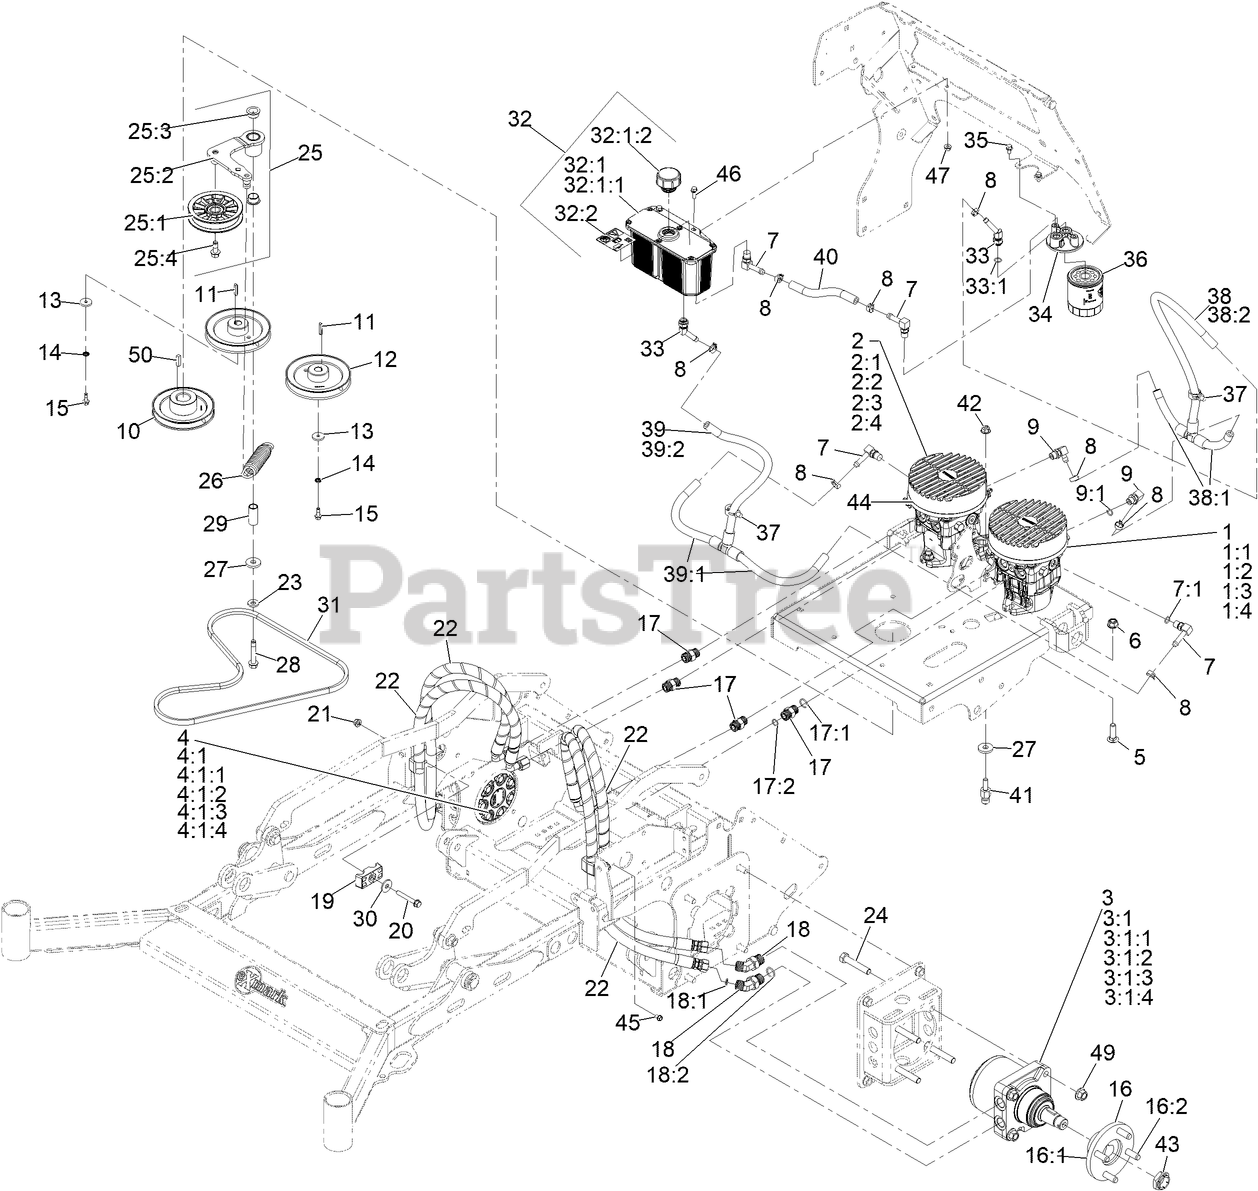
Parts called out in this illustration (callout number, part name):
1	PUMP-12CC LT W/SHOCK VALVE
1:1	KIT, 10CC/12CC PUMP KIT
1:2	SEAL OVERHAUL KIT
1:3	GUARD-PUMP
1:4	PUMP-COOLING
2	PUMP-12CC RT W/SHOCK VALVE
2:1	KIT, 10CC/12CC PUMP KIT
2:2	SEAL OVERHAUL KIT
2:3	GUARD-PUMP
2:4	PUMP-COOLING
3	MOTOR, TL240 LH
3:1	SEAL KIT
4	MOTOR, TL240 RH
4:1	SEAL KIT
5	BOLT-CARR
6	NUT-HF, NI
7	FITTING-ELBOW, 90
7:1	O-RING
8	CLAMP-HOSE
9	FITTING-90 DEG
9:1	O-RING
10	SHEAVE-PUMP, DRIVE
11	KEY, 5MM X 5MM X 29MM
12	SHEAVE-PUMP
13	WASHER-1.00 OD X .25 ID
14	WASHER-SPRING
15	SCREW-HHF
16	WHEEL HUB / STUD ASM
16:1	HUB-WHEEL
16:2	STUD-TYPE, DRIVE
17	FITTING-STRAIGHT
17:1	O-RING
17:2	O-RING
18	Fitting-HYD, 45 DEG
18:1	O-RING
18:2	O-RING
19	CLAMP-TUBE
20	CLAMP-TUBE
21	NUT-HF, NI
22	HOSE ASM-HYD HP
23	WASHER-BELLEVILLE
24	SCREW-HH
25	ASM-PUMP IDLER
25:1	PULLEY-IDLER, FLAT
25:2	ASM-PUMP IDLER ARM
25:3	BUSHING-FLANGE
25:4	SCREW-HFH
26	SPRING, EXTENSION
28	SCREW-HHF
29	PIVOT, IDLER
31	BELT- COG A 54
32:1	RESERVOIR-HYD
32:1:1	Cap-Reservoir, HYD
32:2	DECAL-WARNING
33	FITTING-BARBED, 45 DEG
33:1	O-RING
34	HEAD-FILTER
35	SCREW-HHF
36	FILTER-25 MICRON, BI-DIRECTIONAL
37	CLIP-TIE
38	ASM-HYDRAULIC LO-PRES
38:1	HOSE, LP HYDRO
38:2	HOSE, LP HYDRO
39	ASM-HYDRAULIC LO-PRES
39:1	HOSE, LP HYDRO
39:2	HOSE, LP HYDRO
40	HOSE, LP HYDRO
41	PIN-SPRING, ANCHOR
42	NUT-HF, NI
43	LOCKNUT
44	TIE-CABLE
46	SCREW-HHF
47	NUT-HHF
49	Nut-Lock 1/2-13
